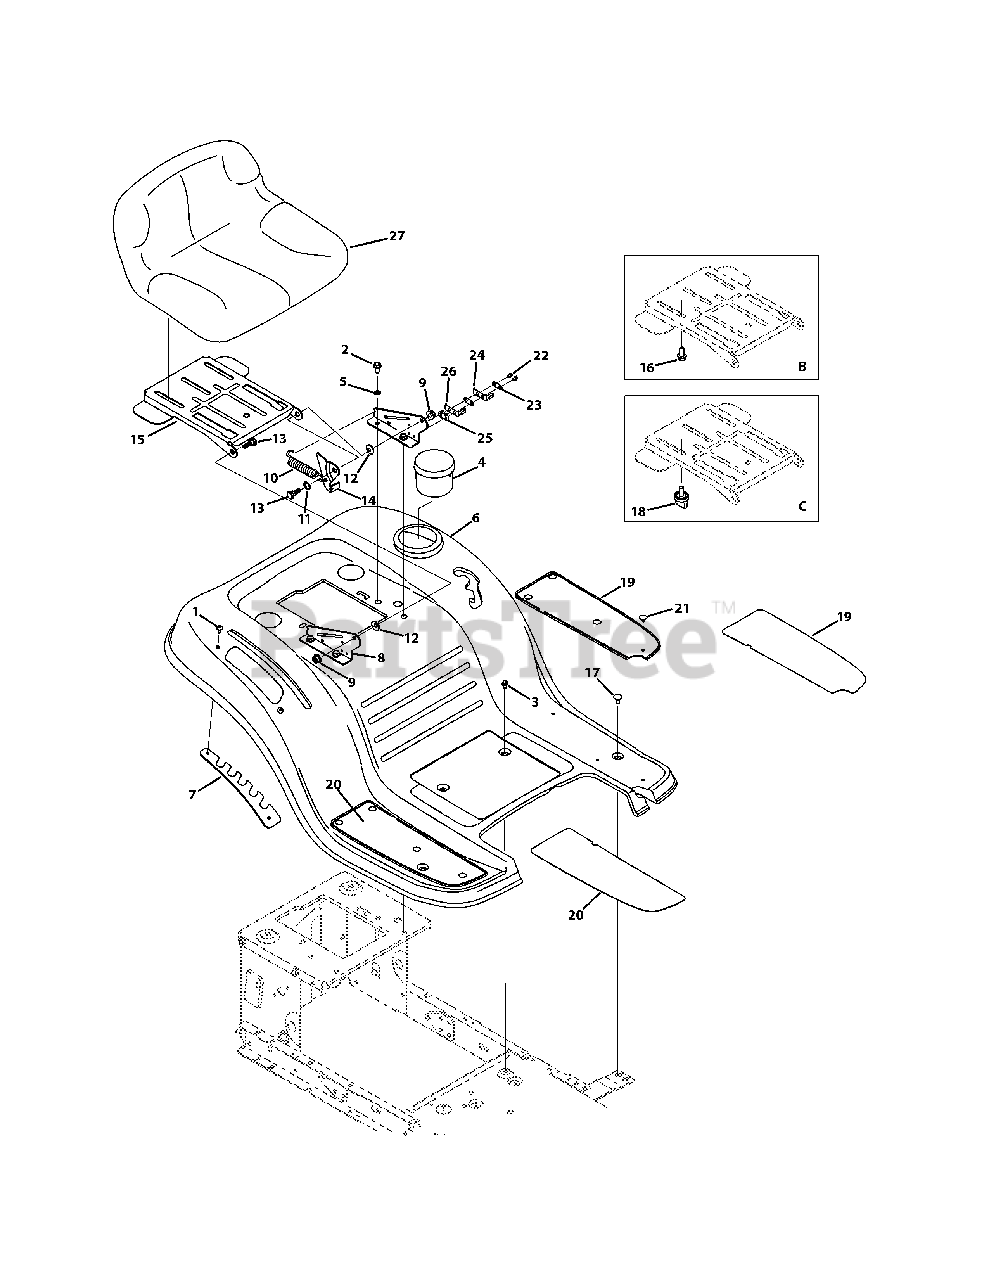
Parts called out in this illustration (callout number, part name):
1	Screw, 1/4-20 x .500
2	Screw, 5/16-18 x .750
3	Screw Pan Torx Head, 1/4-20 x .500
5	Loack Washer, 5/16
6	Fender - Red
7	Lift Adjuster Bracket - Powder Black
7	Lift Adjuster Bracket -Red
8	Seat Mount Bracket - Powder Black
8	Seat Mount Bracket - Red
9	Flangelock Nut, 5/16-18
10	Extension Springing
11	Flat Washer, .510x .750 x .033
12	Bell Washer, .340 x .872 x .060
13	Shoulder Screw, 5/16-18 x .437 x .268
14	Lift Seat Bracket
15	Pivot Seat Manual Adjust Bracket - Black
15	Pivot Seat Manual Adjust Bracket - Red
16	Hex Head Flange, 3/8-16 x .875
17	Screw Carriage, 1/4-20 x .62
18	Knob, 3/8-16 x .875
19	Foot Pad, LH
19	Foot Pad, Abrasive, LH
20	Foot Pad, RH
20	Foot Pad, Abrasive, RH
21	Ratchet Clip, .250 x .500
22	Screw, 8-18 x .500
23	Insulator Plate
24	Outer Seat Springing
25	Insulator Boss Plate
26	Inner Seat Springing
27	Low Back Seat, Black, Set-up B or C
